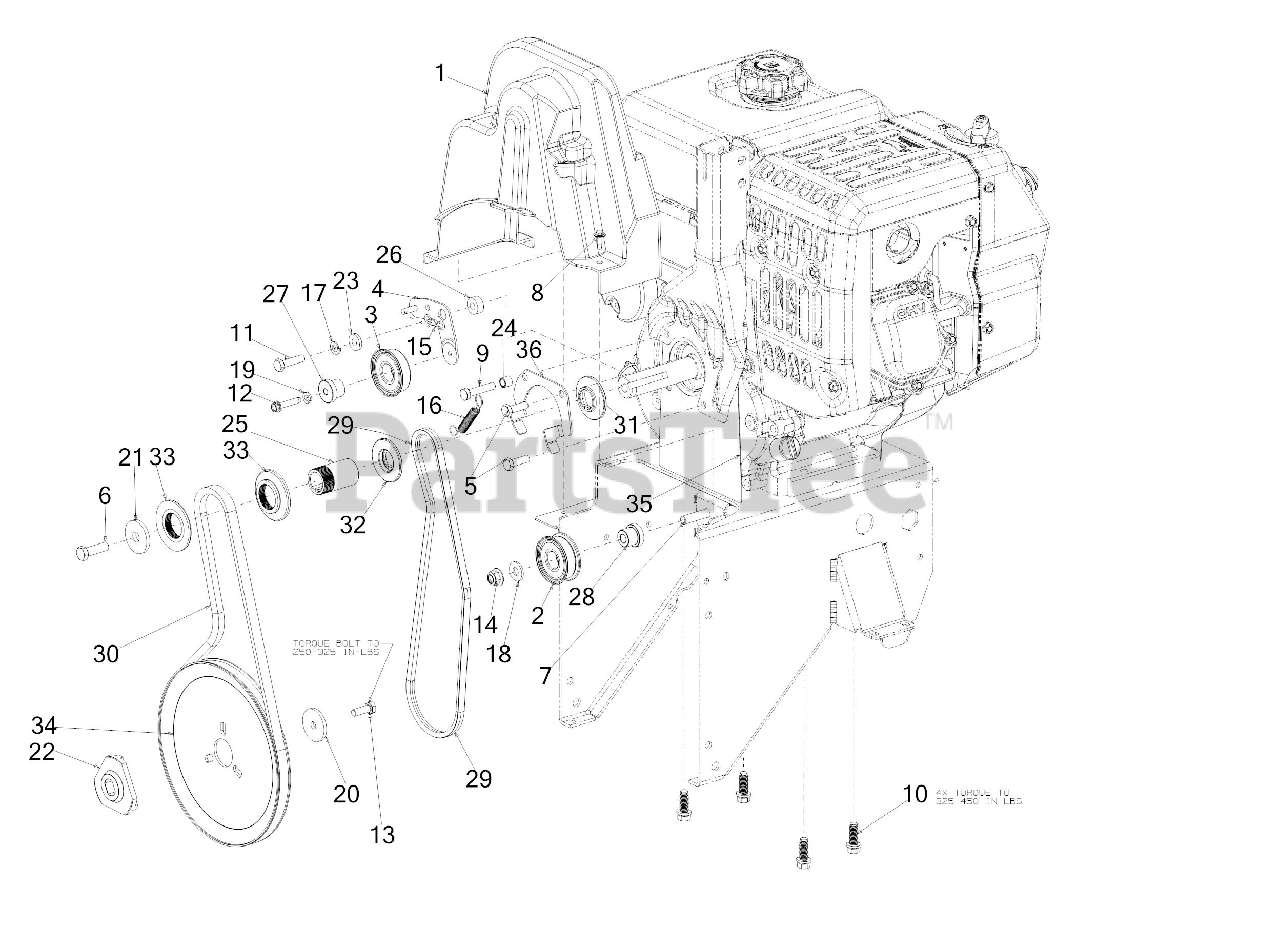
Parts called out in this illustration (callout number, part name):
1	BELT COVER ASSEMBLY
2	IDLER PULLEY ASSEMBLY
3	IDLER PULLEY ASSEMBLY
4	HYDRO DRIVE IDLER ASSEMBLY
5	HEX HEAD CAP SCREW 5/16-24 x 1.00 GR5
6	SCREW 3/8-24X1.25
7	SCREW 3/8-16 x 1.50
8	SCREW M6-1 x .625
9	SCREW 5/16-24 x 1.5 GR5
10	SCREW 3/8-16 x 1
11	SCREW 5/16-24 x 1.25 GR5
12	SCREW 1/4-20 x 1.25
13	SCREW 5/16-24 x .875 GR5
15	BOW TIE COTTER PIN 1/4-5/16
16	EXTENSION SPRING 2.675
17	LOCK WASHER 5/16
18	FLAT WASHER .385X.870X.090
19	LOCK WASHER
20	FLAT WASHER
21	FLAT WASHER .45 x 1.5 x .172 HT
22	ADAPTER PULLEY .75 DIA W/DD
23	SHOULDER SPACER
25	PULLEY SPACER
26	IDLER BRACKET SPACER .340X.750X.330
27	SHOULDER SPACER
28	SHOULDER SPACER .385 x .785 x .538
29	HYDRO DRIVE BELT
30	AUGER BELT .500 X 41.40
31	HALF PULLEY 3/8-V x 2.2
32	HALF PULLEY-3/8 V x 1.7160
33	HALF PULLEY 4L-V x 2.40 OD
34	AUGER PULLEY 8.5 OD
35	ENGINE PLATE (FRONT COVER)
36	BELT KEEPER BRACKET
